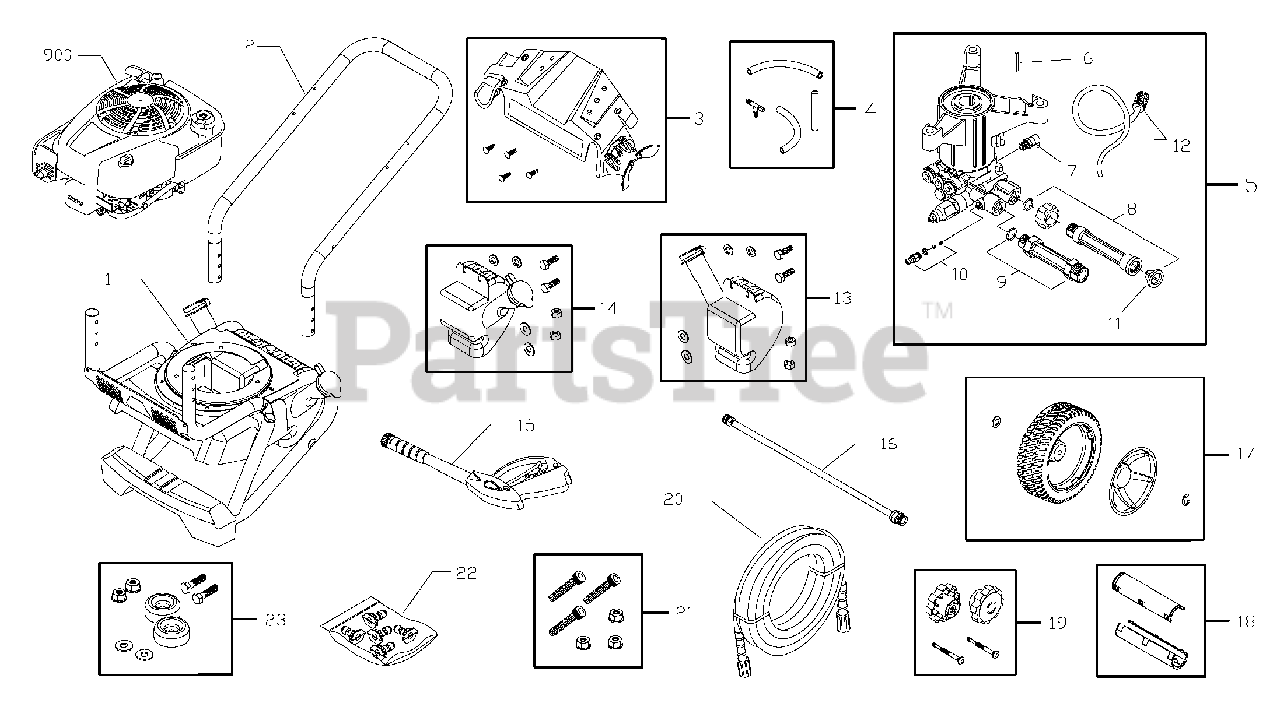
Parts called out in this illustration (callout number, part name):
7	VALVE, Thermo Relief
8	KIT, Water Inlet
10	KIT, Chemical Injection
11	FILTER, Garden Hose
15	GUN
16	EXTENSION, QC
19	KIT, Hardware, Handle
21	KIT, Hardware, Pump Mounting
22	KIT, QC Nozzles
23	MOUNT, Vibration
900	* ENGINE
